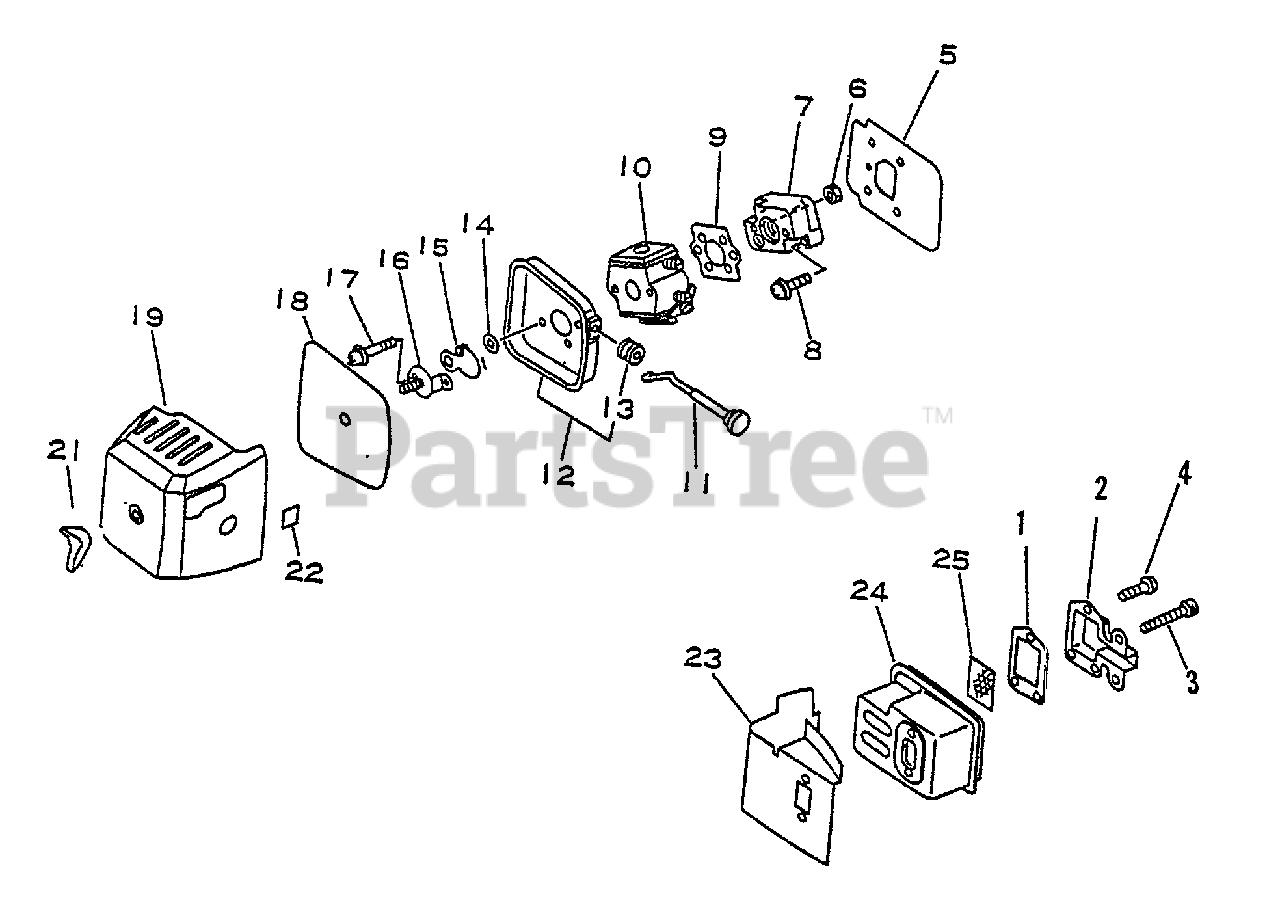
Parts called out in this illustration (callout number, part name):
1	GASKET, EXHAUST
2	GUIDE, EXHAUST
3	SCREW - 5X50
4	SCREW - 4X10
5	GASKET, INTAKE
7	INSULATOR, INTAKE
8	SCREW - 5X20
9	GASKET, INTAKE
10	CARBURETOR
11	ROD, CHOKE
12	CASE, AIR FILTER
14	WASHER - 5
15	SHUTTER, CHOKE
16	PLATE, PREVENT
17	SCREW - 5X57
18	FILTER, AIR
19	COVER, AIR FILTER
21	WINGNUT - 5
22	LABEL - CHOKE
23	COVER, EXHAUST
25	SCREEN, SPARK ARRESTOR
